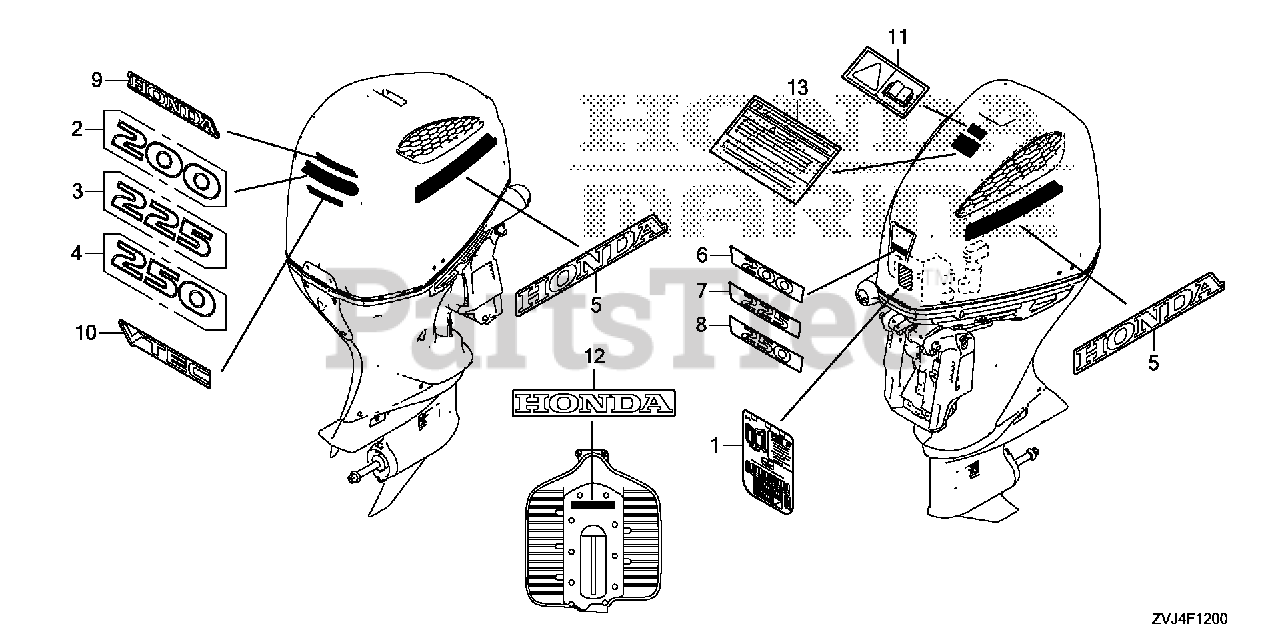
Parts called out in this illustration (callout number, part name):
1	LABEL, FUSE & OIL CAUTION (E)(M)
2	MARK, RR. (BF200)
5	MARK, SIDE STRIPE (BF250)
6	MARK, FR. EMBLEM (BF200)
9	MARK, HONDA
12	EMBLEM (13 (HONDA)
13	LABEL, WARNING OPERATOR
